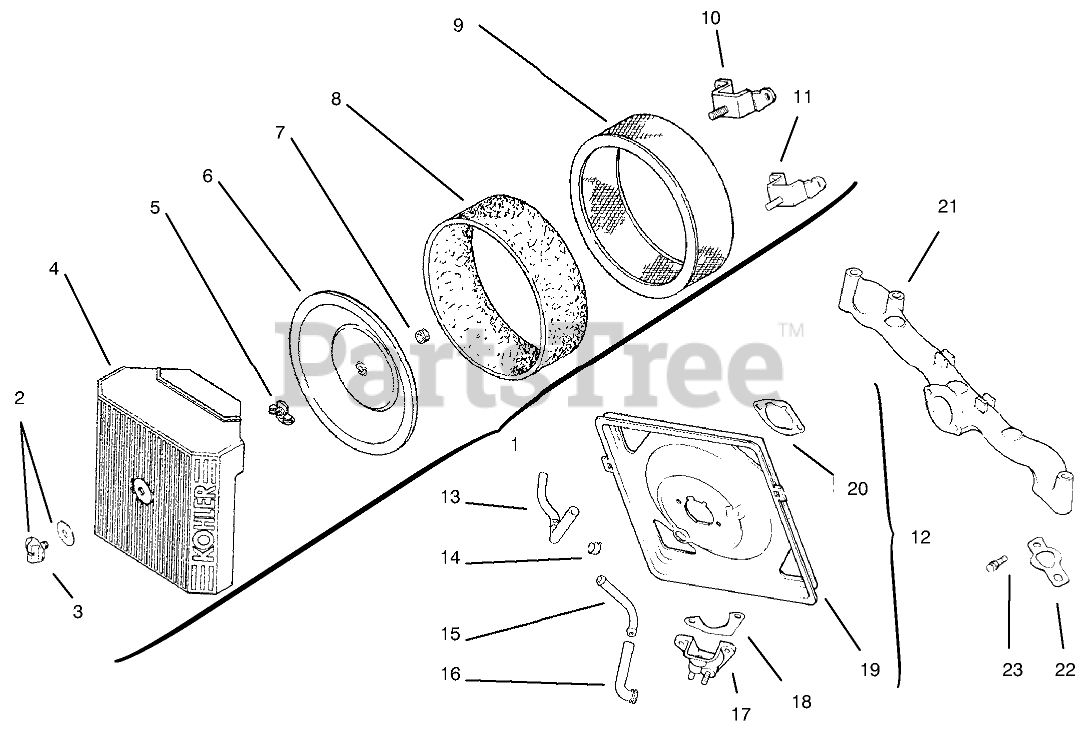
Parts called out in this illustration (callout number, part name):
1	Kit-A/C Cover INC 2-4
2	Spring-Latch
3	Latch-Lever
4	Pin-Latch Lever
5	Wingnut
6	Seal, insert
7	Cover-Inner AirCleaner
8	Bement-Precleaner
9	Bement-Air Cleaner
10	Cup-Fuel Spitback
11	Gasket-Fuel Spitback
12	Base-Air Cleaner
13	Gasket-A/C Base
14	Manifold-Intake
15	Gasket-Intake, Manifold
16	Screw
